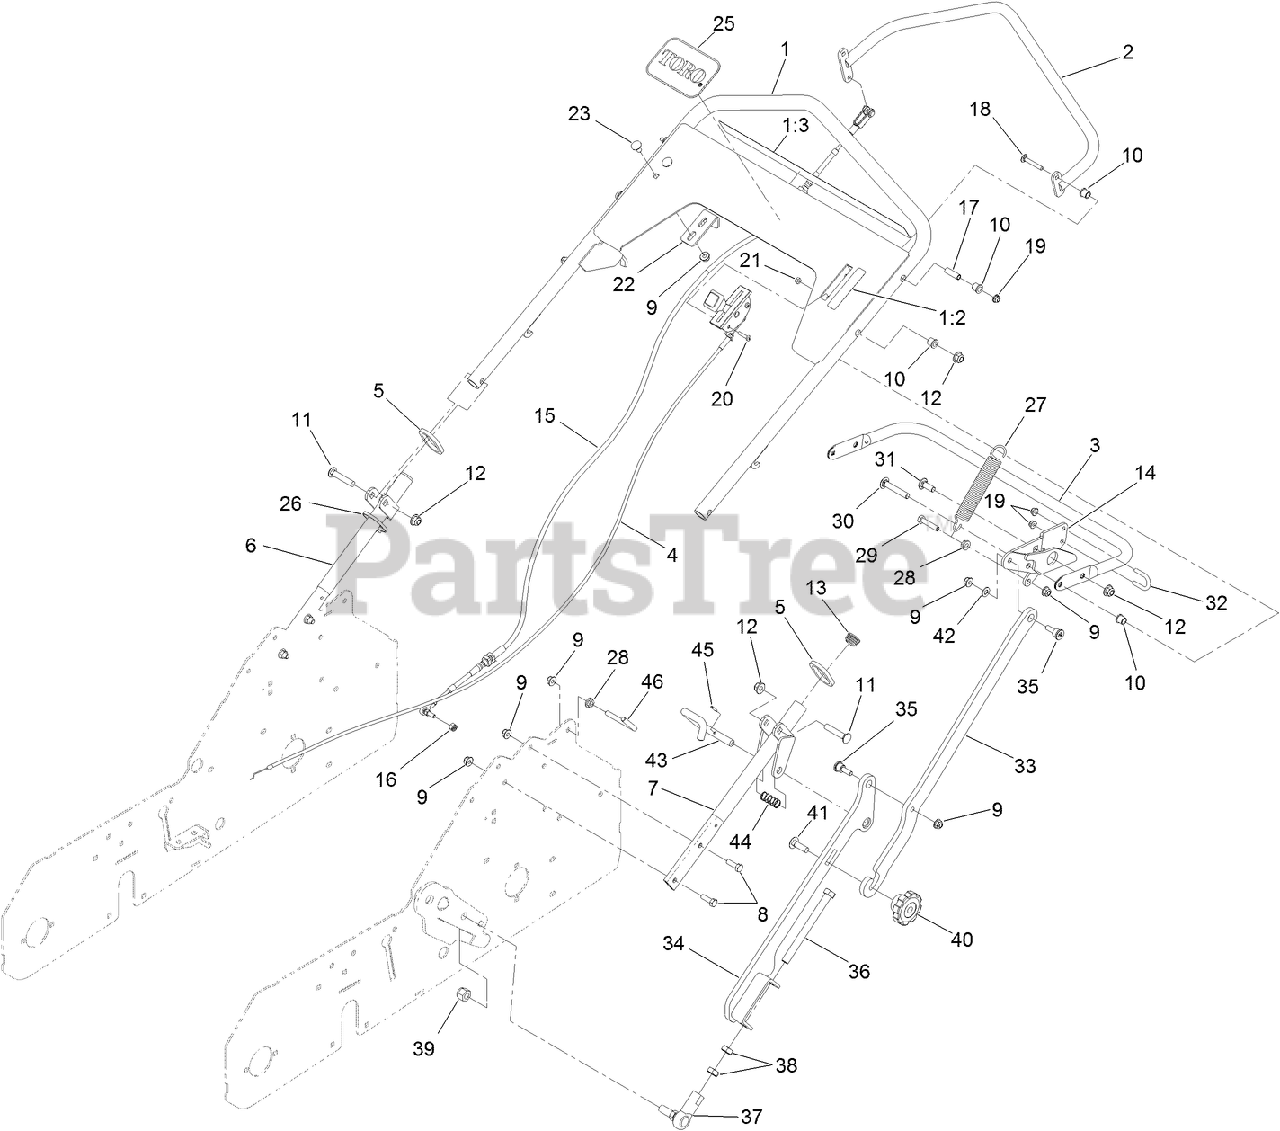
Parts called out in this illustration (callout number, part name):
1	HANDLE ASM
1:2	DECAL-THROTTLE, CHOKE
1:3	DECAL-AERATOR CONTROL PANEL
2	TUBE-CONTROL
3	TUBE-HANDLE LIFT
4	CONTROL-THROTTLE
5	RING-HANDLE LOCK
6	HANDLE-LOWER
7	HANDLE-LOWER, LH
8	SCREW-HH
9	NUT-HF, NI
10	BEARING
11	SCREW-CARR
12	NUT-HF, NI
14	ARM-UPPER
16	NUT-LOCK
17	BUSHING-PIVOT
18	SCREW-CARR
19	NUT-HF
20	SCREW-PPH
21	NUT-LOCK, NI
22	ANGLE-STOP
23	SCREW-CARR
25	DECAL
26	TIE-CABLE
27	SPRING-EXTENSION
28	NUT-HF
29	SCREW-HH
30	BOLT-CARR, SHORT NECK
31	SCREW-CARR
33	ARM-UPPER
34	ARM-LOWER
35	BOLT-SHOULDER, GROOMER
36	SCREW, HH
37	END-ROD, RH THREAD
38	NUT-JAM
39	NUT-HEX
41	BOLT-CARR
42	WASHER-PLAIN
43	PIN-LATCH, TRANPORT
44	SPRING-COMPRESSION
45	PIN-SPRING
46	KEEPER
